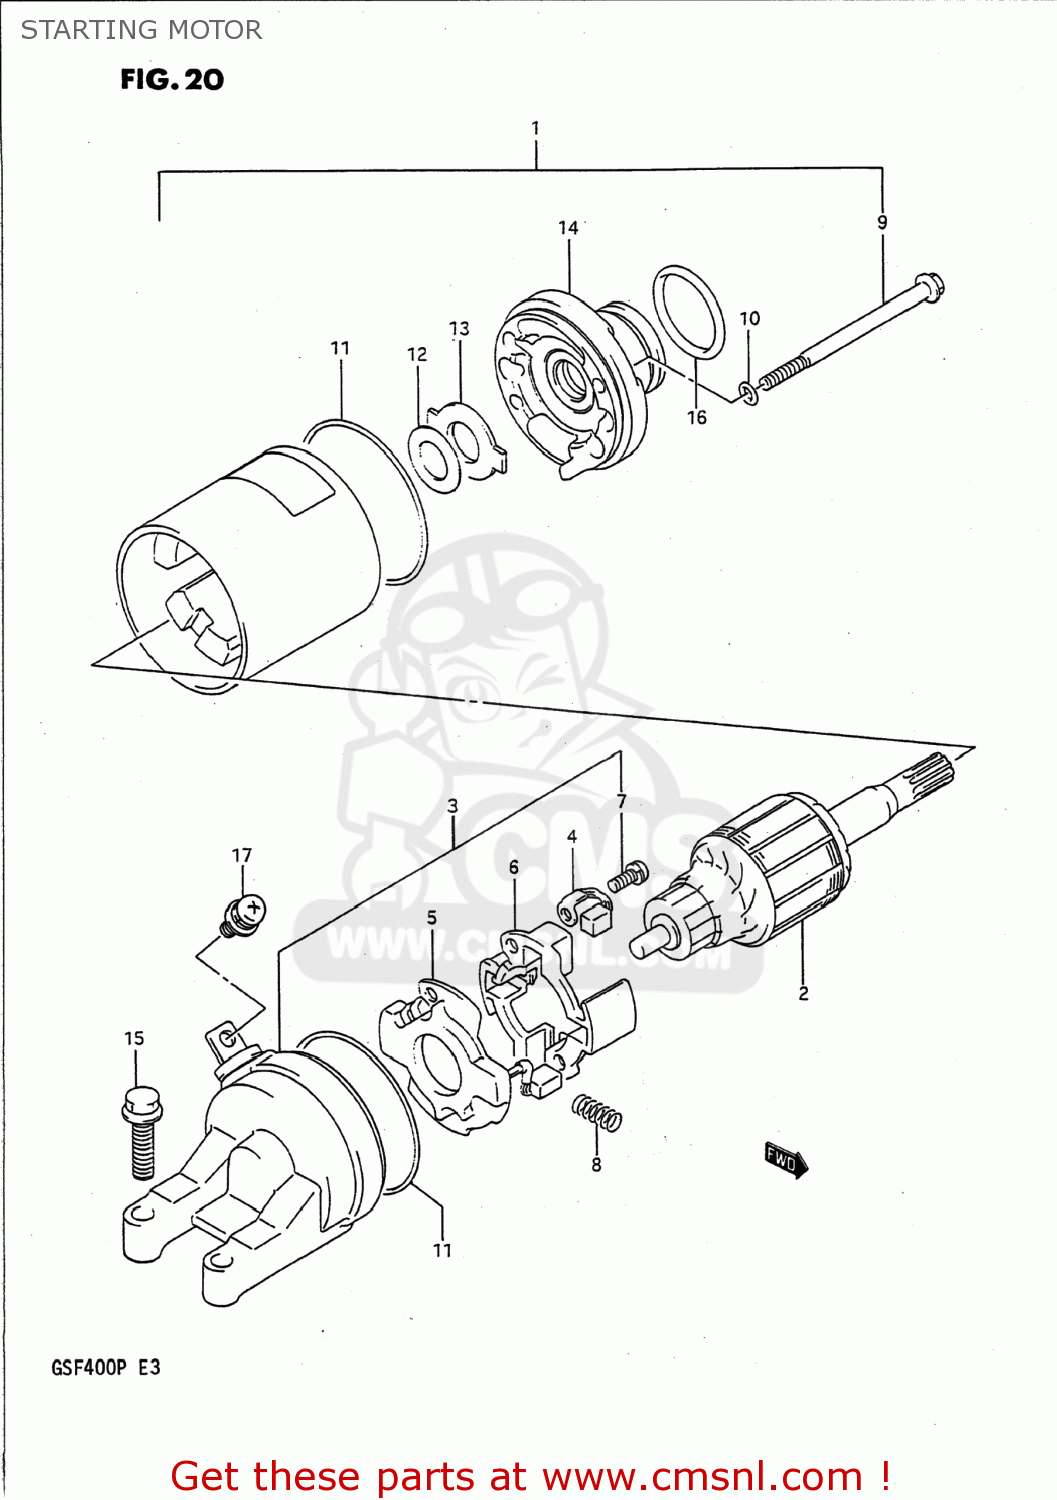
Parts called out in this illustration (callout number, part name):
1	MOTOR ASSEMBLY,STARTING
2	ARMATURE
3	FRAME ASSEMBLY,COMMUTATOR
4	BRUSH
5	BRUSH SUB ASSEMBLY
6	HOLDER,BRUSH
7	SCREW
8	SPRING
9	BOLT
10	O RING
11	O RING
12	SHIM
13	PLATE,LOCK
14	BRACKET
15	BOLT(6X23)
16	O RING(D:3,ID:24.5)
17	SCREW
